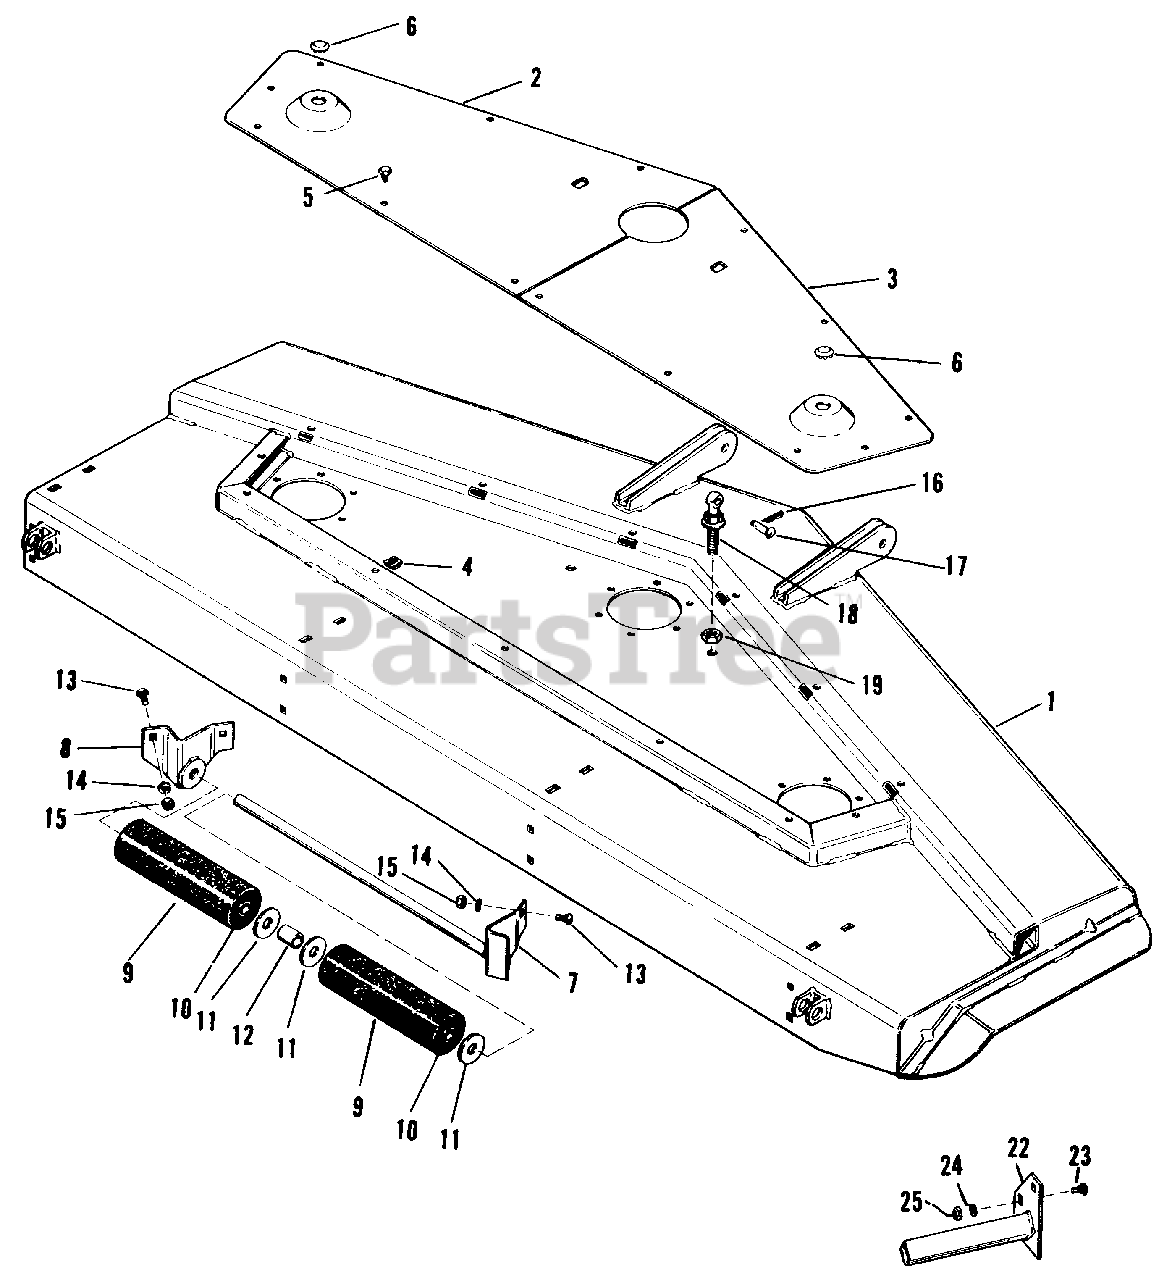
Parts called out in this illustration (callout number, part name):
1	Deck Assembly
2	Cover Plate, L.H.
3	Cover Plate, R.H.
5	Self Tapping Screw, 5/16"-12
6	Plug Button
7	Bracket & Shaft Assy.
8	Bracket Assembly
9	Roller w/Bushing
13	Carriage Bolt 5/16"-18 x 3/4" lg.
14	Lock Washer, 5/16"
15	Hex Nut, Full, 5/16"-18
16	Spring Clip
18	Eyebolt Assembly
19	Hex Nut, Jam. 7/16"-14
22	Stone Guard Assembly
23	Carriage Bolt, 3/8"-16 x l" lg.
24	Lock Washer, 3/8"
25	Hex Nut, Full, 3/8"-16
